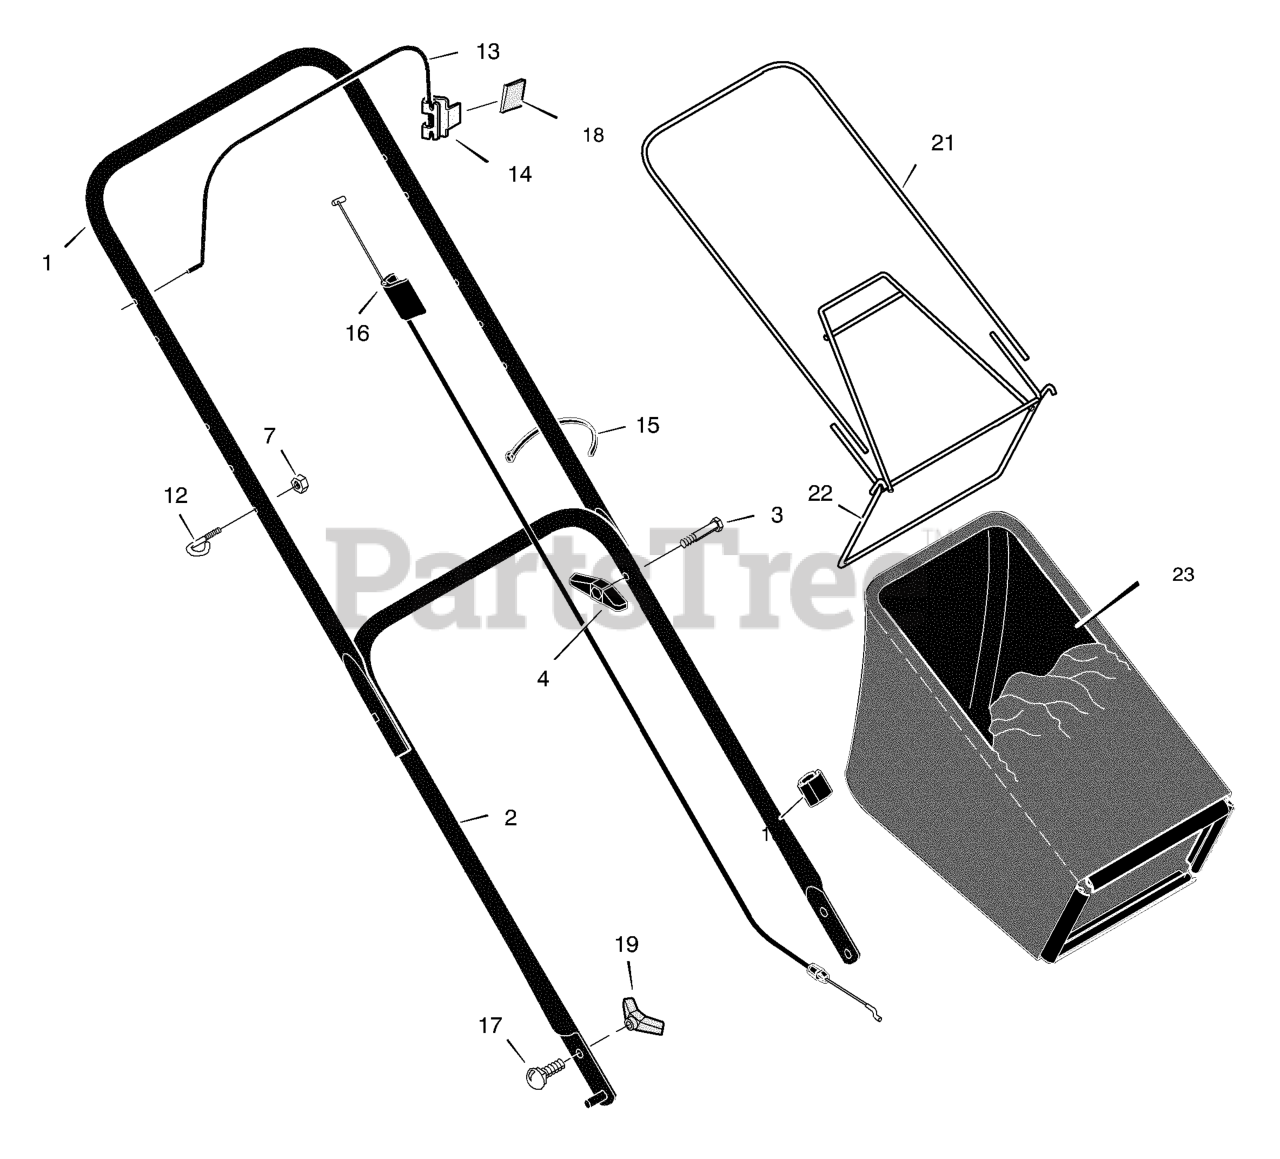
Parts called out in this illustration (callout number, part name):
1	Handle, Upper (Black)
2	Handle, Lower (Black)
4	Knob, Plastic
7	Locknut
12	Guide, Rope
13	Engine Stop Lever
14	Bracket, Stop Lever
15	Fastener, Cable
16	Engine Stop Cable
17	Bolt, Carriage
19	Knob, Plastic
21	Tube, Bag
22	Frame Assembly
23	Bag, Cloth - Black
